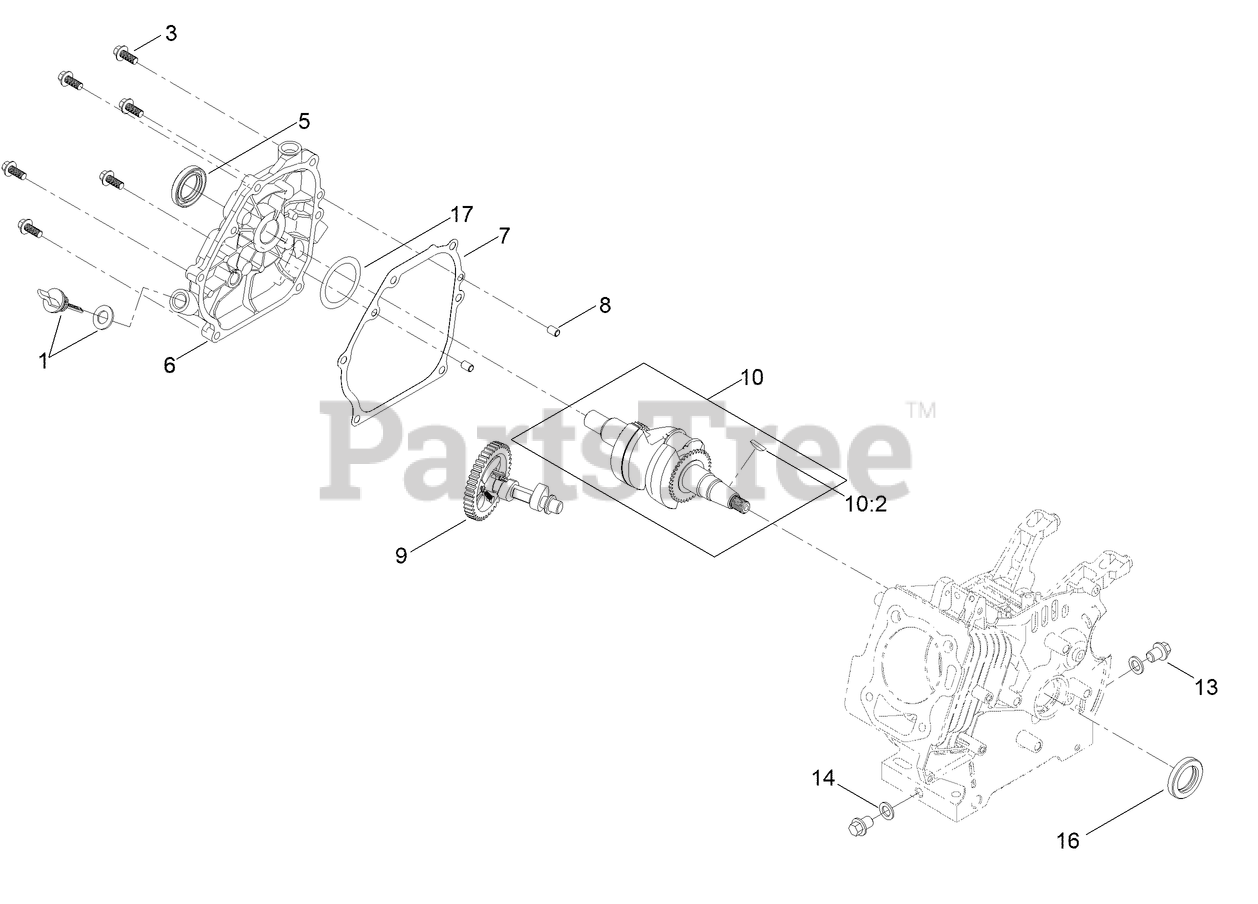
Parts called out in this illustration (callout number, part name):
1	DIPSTICK AND O-RING KIT
3	SCREW-HHF
5	SEAL-OIL
6	COVER-CRANKCASE
7	GASKET-COVER, CRANKCASE
8	PIN-DOWEL
9	CAMSHAFT ASM
10	CRANKSHAFT ASM
10:2	KEY-WOODRUFF
13	SCREW-HHF
14	WASHER-PLAIN
16	SEAL-OIL
17	WASHER-THRUST
